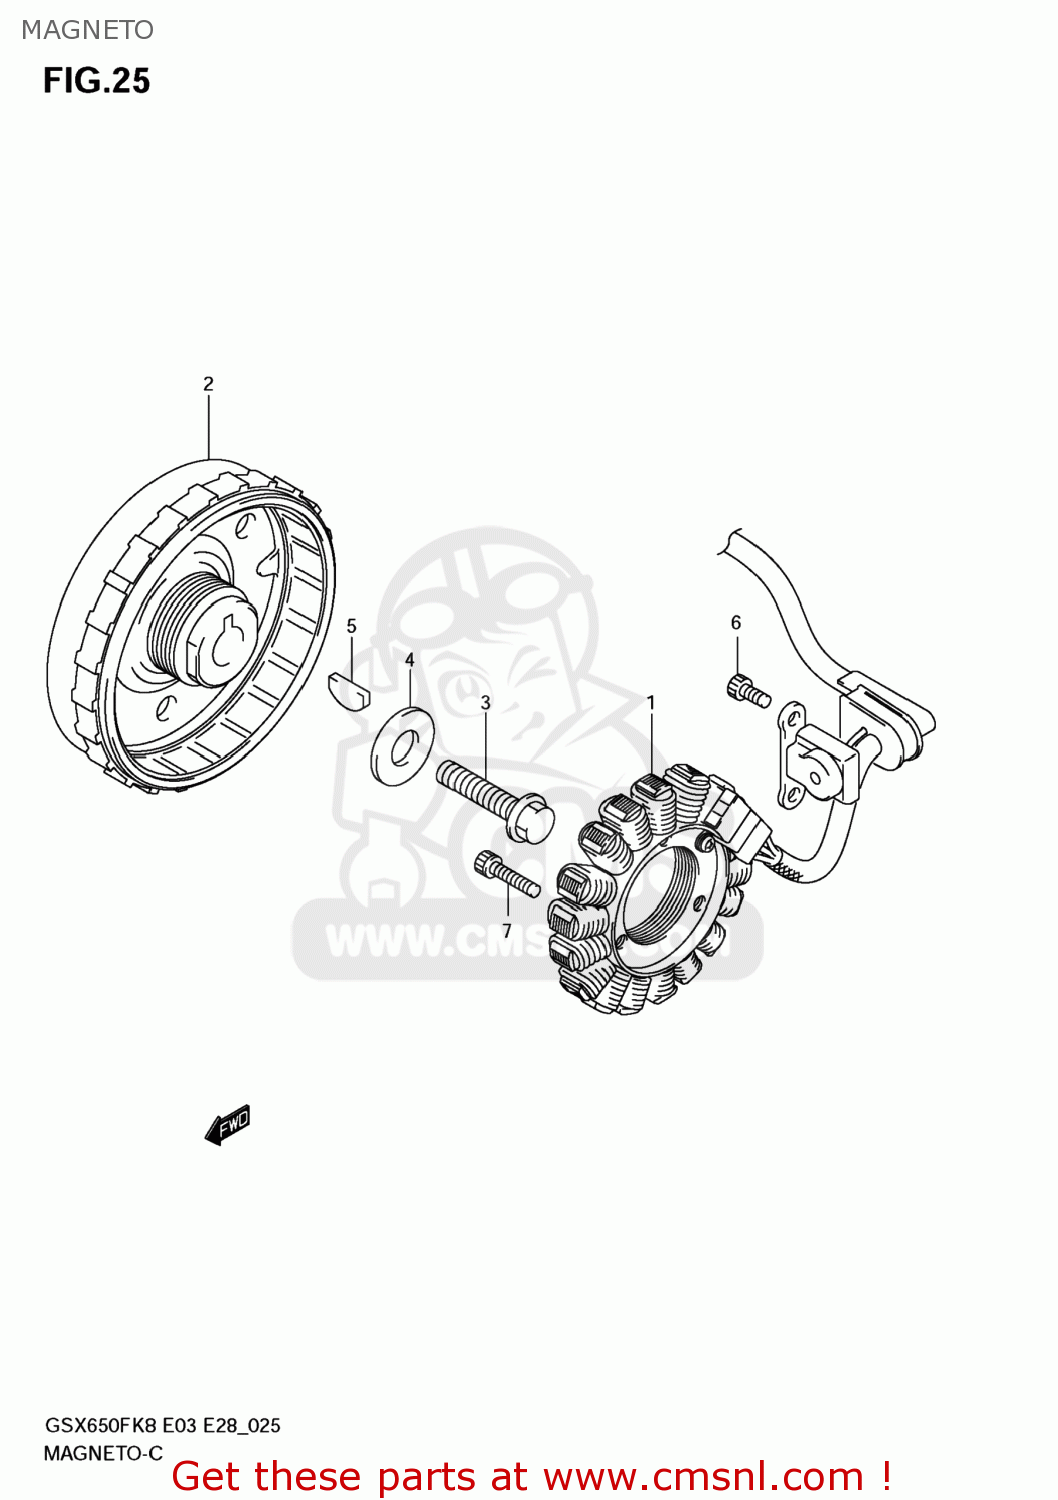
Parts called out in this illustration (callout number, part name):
1	STARTER ASSY
2	ROTOR ASSY
3	BOLT(12X40)
4	WASHER(12X30X3)
5	KEY
6	BOLT
7	BOLT
